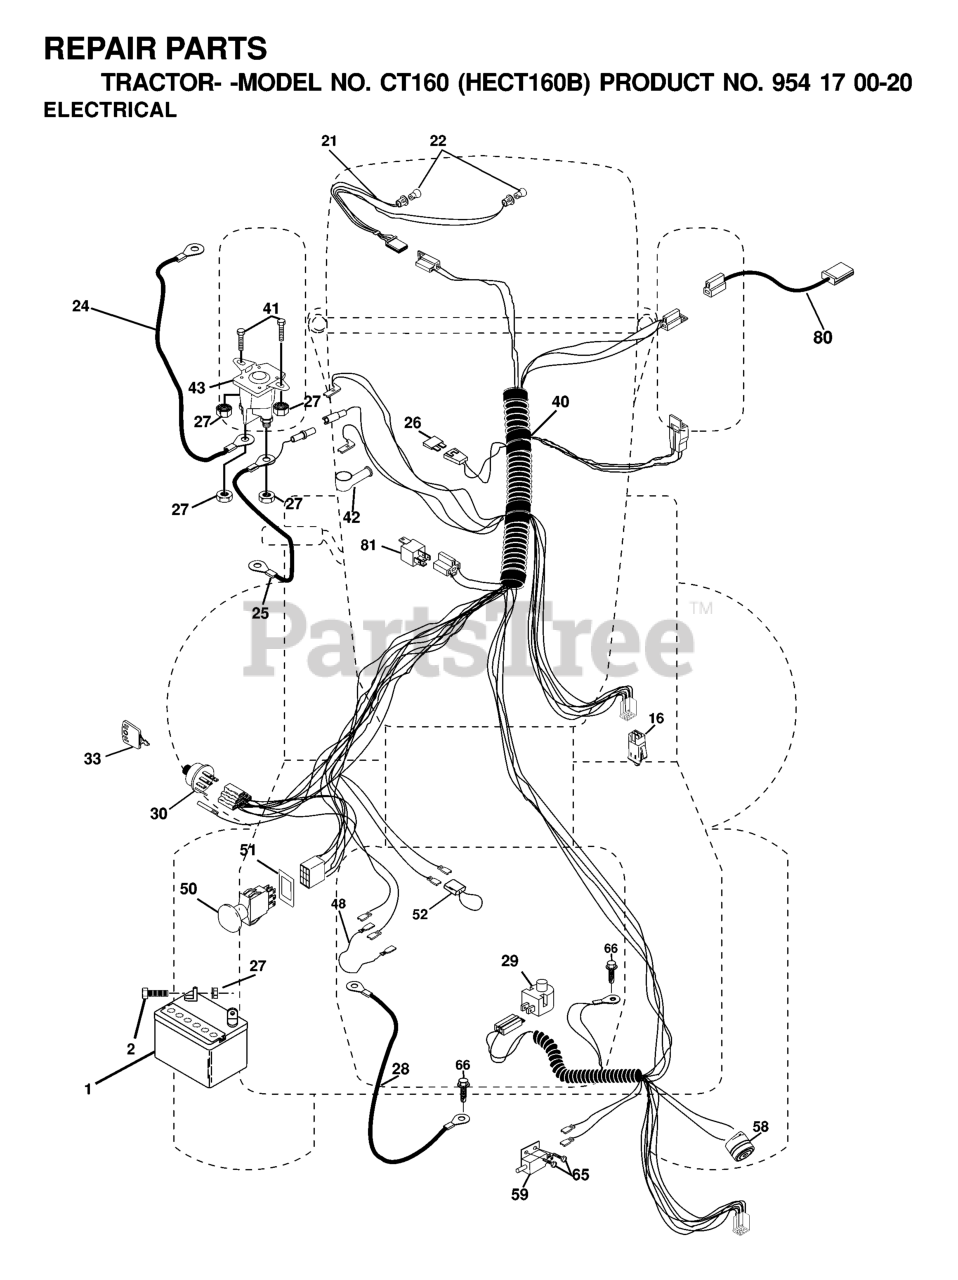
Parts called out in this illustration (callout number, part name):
1	BATTERY 12 VOLT 25 AMP
2	BOLT.HEX.1/4.X.3/4.DICHROMATE
16	SWITCH INTERLOCK
24	BATTERY CABLE GT
25	CABLE BATTERY
26	FUSE 15 AMP
27	NUT
28	CABLE GROUND
29	PLUNGER SWITCH (COLOR:OLIVE)
30	SWITCH IGN
33	KEY MLD GEN DELTA
40	HARNESS.ING.CRD.ELECT
41	BOLT
42	TERMINAL COVER
43	SOLINOID
48	ADAPTER.AMMETER
50	PTO SWITCH
51	FRAME RETAINING RING
52	WIRE PROTECTION LOOP
58	BUZZER
65	Screw, Hex Wsh. Tap #10-16 x 1/2
80	HARNESS, CLUTCH
81	RELAY.ASSY.T
